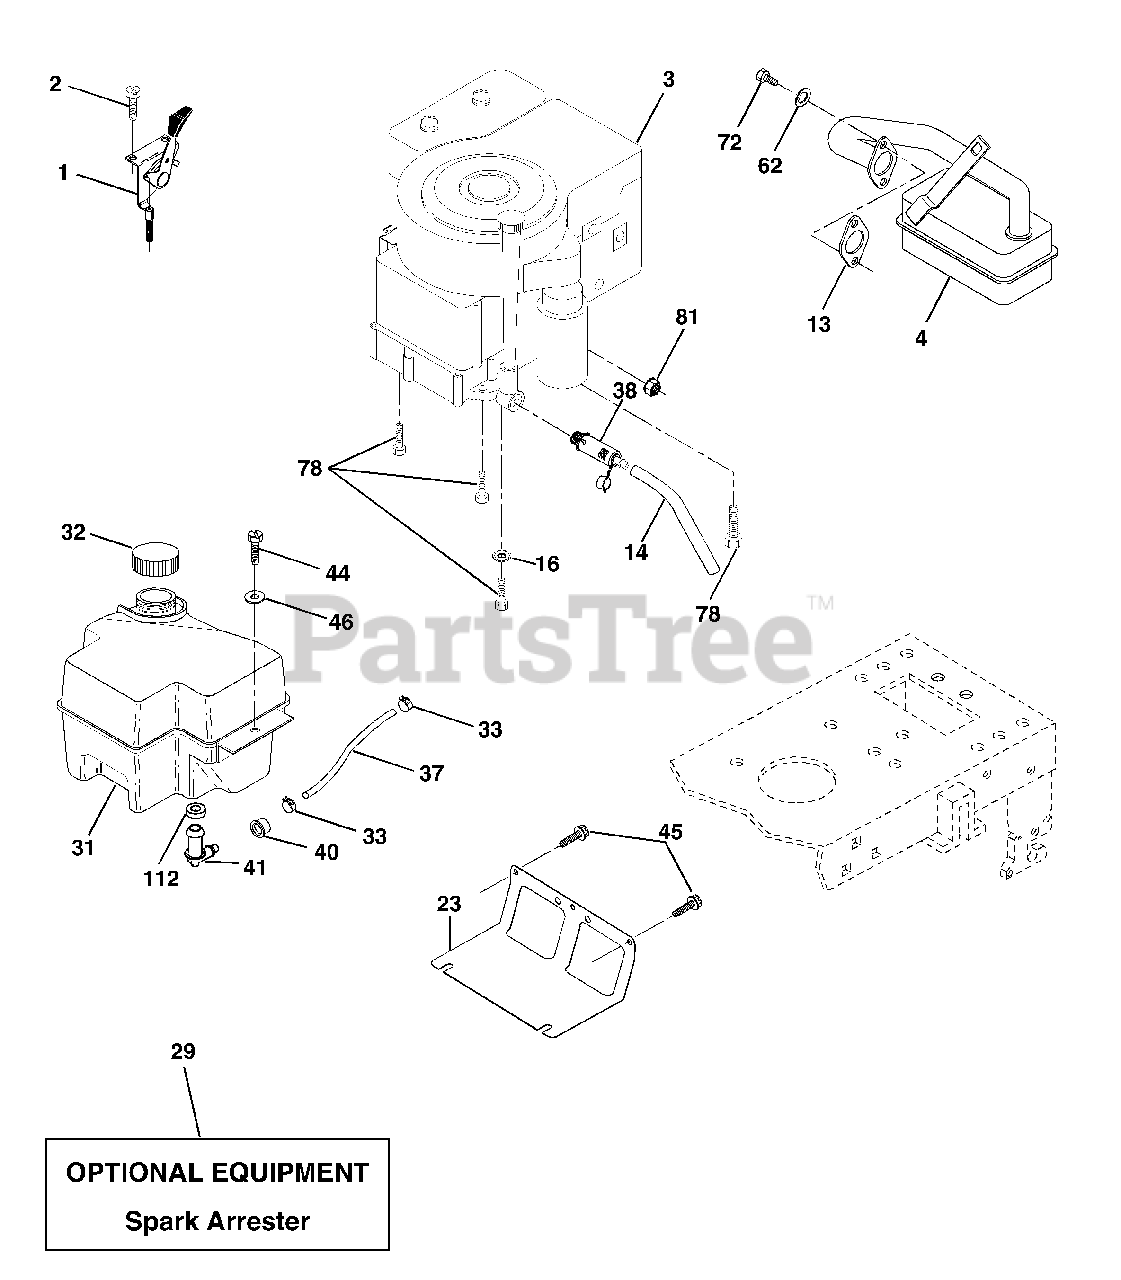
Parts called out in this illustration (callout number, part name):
1	Control Th/ch Flag
2	Screw Hex Thd Cut 1/4-20x5/8 T
4	Muffler Exhaust
5	Exhaust Tube LH
6	Exhaust Tube RH
8	Bolt 5/16-18 UNC x 3/4
10	Shield Browning
11	Washer Lock 5/16
12	Screw Hex 5/16-18 x 3/4
13	Gasket Muffler
14	Nipple Pipe 3/8 NPT x 4-1/2
15	Elbow STD 90 Degree 3/8-18
16	Washer Lock Ext Tooth 3/8
17	Screw 3/8-16 x 1-1/2
23	Shield Brn/Dbr Guard
25	Control Choke
26	Nut Keps 3/8-24 Unf
29	Arrestor Spark
31	Tank Fuel Front 2 00
32	Cap Fuel
33	Clamp Hose Black
37	Line Fuel 20"
38	Plug Oil Drain
40	Bushing Snap Nyl Blk Fuel Line
41	Stem Tank Fuel
44	Screw Hex wsh Thdrol 1/4-20x3/4
45	Screw Hex Wsh Thdrol 3/8-16 x 3/4
46	Washer 9/32 X 7/8 X 16 Ga
81	Nut Keps Hex 1/4-20 Unc
112	Bushing
